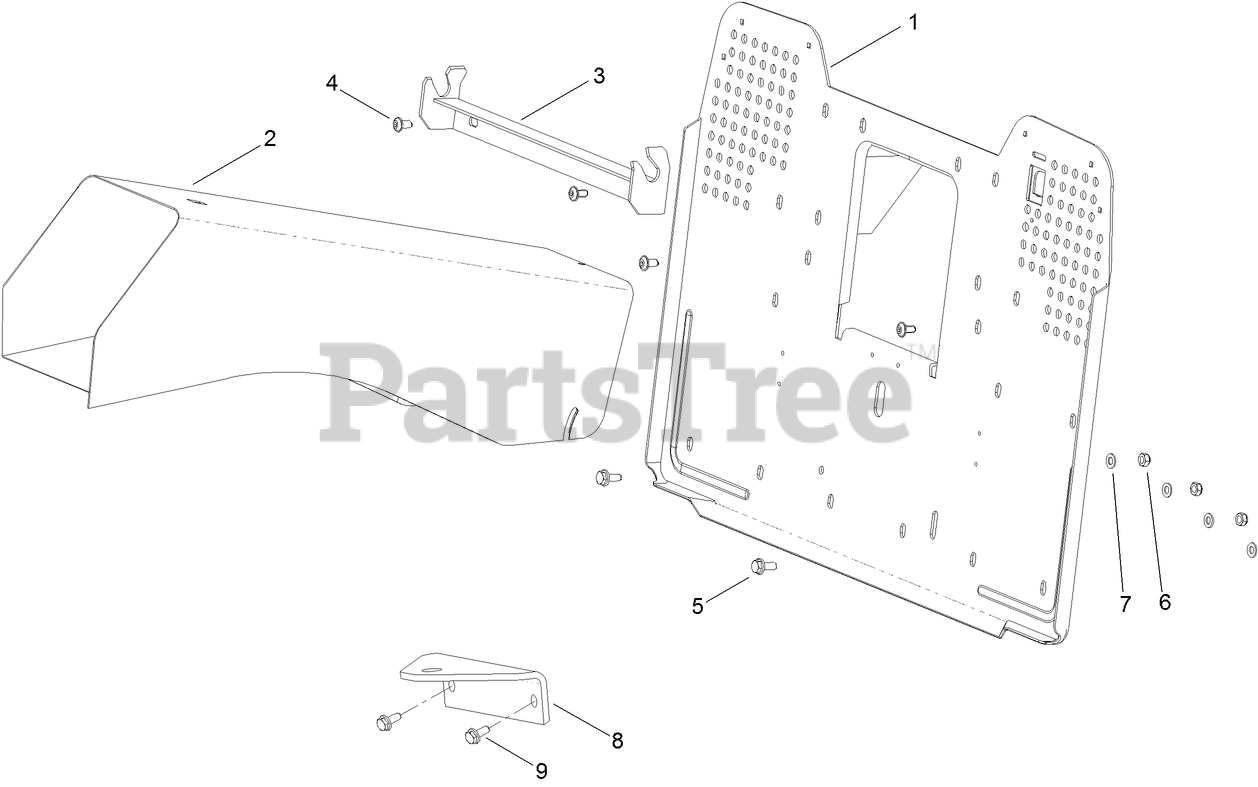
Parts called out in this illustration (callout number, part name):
1	COLLECTOR PLATE ASM
2	TUNNEL
3	SUPPORT-COLLECTOR
4	BOLT-CARRIAGE
6	NUT-LOCK, NI
7	WASHER-PLAIN
8	HITCH-TOW
9	SCREW-HHF
